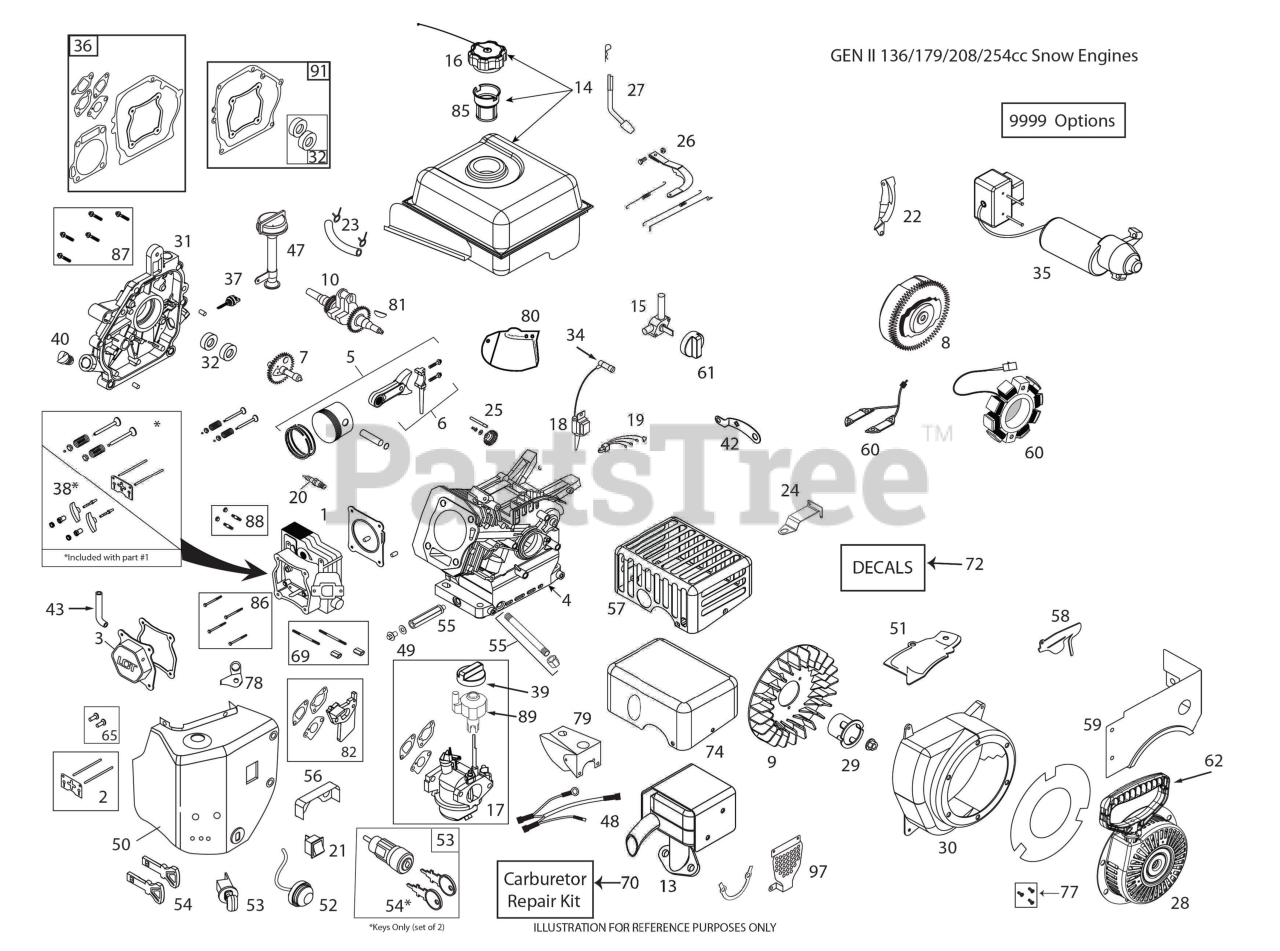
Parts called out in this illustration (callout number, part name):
1	CYLINDR.HEAD.SRV.KIT W/GASKET
2	KIT.PUSH.ROD.SRV(SK208-1001)
3	VALVE COVER ASSEMBLY
5	KIT.PISTON.SRV(SK208-1400)
6	KIT.CONNECT.ROD.SRV(SK208-1500
7	KIT.CAMSHAFT.208CC.LCT
8	FLYWHEEL ELECTRIC START W/6 MA
9	FLYWHEEL FAN 420586
10	CRNKSHFT-KYD#14.208CCSKSNO8001
13	MUFFLER KIT LCT SKSN2205.1
14	FUEL.TK.ASSY.GENII.SKSN0311.1
15	FUEL.PETCOCK.SNOW(SKSN4900)
16	FUEL CAP OVERSIZED CLICK STYLE
17	CARBURETTOR L10-1D.W/SP
18	208CC IGN COIL (STD)
20	SPARK.PLUG(2083810)
21	SWITCH.ON/OFF(SKSN-0403)
22	SHIELD.FLYWHEEL.ELEC.STRT.208C
23	FUEL HOSE KIT
24	SPEED.CTRL.BRKT.(SKSN0150)
25	GOVENOR.GEARS ASM(SK2082900)
26	CARBURETTOR GOVERNOR LINK.ASM.
27	KIT.GOVERNOR.CRANK(SK208-3100)
28	RECOIL.STRT.ROUND(BLK) SNOW
29	STRTER.CUP(NON-SLOT)SKSN0601.2
30	BLOWER HOUSING ASSY
31	COVER CRANKCASE.LCT.SK2083605
32	SEAL KIT (2 PCS)
34	SPARK.PLUG.BOOT.SNW,SKSN4691.1
35	STARTER 230C EL START.LCT SKSN
36	GASKET.KIT.208CC(SK2084300.1)
37	DIPSTICK SMALL
38	ROCKER ARM KIT
39	CHOKE.KNOW.SNOW(SKSN4500)
40	NON REMOVABLE PLUG
43	TUBE.BREATHER.LCT.208
47	TUBE ASSY HIGH OIL-FILL
48	HARNESS WIRE. W/O OFF/ON SWITC
49	KIT.OIL.DRAIN.PLUG(SK2089911
50	BOX HEATER.W/O OFF/ON SWITCH.L
51	SHIELD.CYLINGER.LCT.SKSN0608.1
52	PRIMER.BULB.WITH HOSE (SNOW)
53	SWITH.KEY.ASSEM.SNOW.SINGLE.ST
54	KEY SET(2 KEYS) SKSN0407.1
55	EXTENDED OIL DRAIN TUBE
56	SHIELD.VAPOR.SNOW
58	SHIELD GOVENOR & CARB - COMPOS
59	FUEL.TNK.SKRT.GENII.SKSN0103.1
60	208CC 60W ALTERNATOR
61	FUEL KNOB-SNOW
62	STARTER.GRIP.SNOW.LCT.SKSN0603
65	TAPPET.KIT.LCT.208CC
69	CARB.STUDS & COUPLING KIT.SNOW
70	CARBURETOR.REPAIR KIT.LCT.
72	ARIENS 414 SNOW DECAL KIT
74	MUFFLER GUARD.EUR./LCT.SKSN220
77	BOLT.KIT.RECOIL.LCT.ALL.ENGINE
79	COVER.CARBURETOR.SNOW
81	KEYS.FLYWHEEL.208/414CC.5PACK
82	SPACER.CARBURETOR.208CC.LCT
85	STRAINER.FUEL.TANK.LCT.208CC
86	KIT.BOLT.CYLINDER.HEAD.(4PC)
87	KIT.BOLT.CRANKCASE.COVER.6PC
88	STUD.MUFFLER.KIT.LCT
89	KNOB LCT.SKSN5325.1 SPEED
91	COVER CRANKCASE GASKET
97	MUFFLE MANIFOLD GUARD.LCT
9999	KIT.BOLT.LCT.SK9990.1
